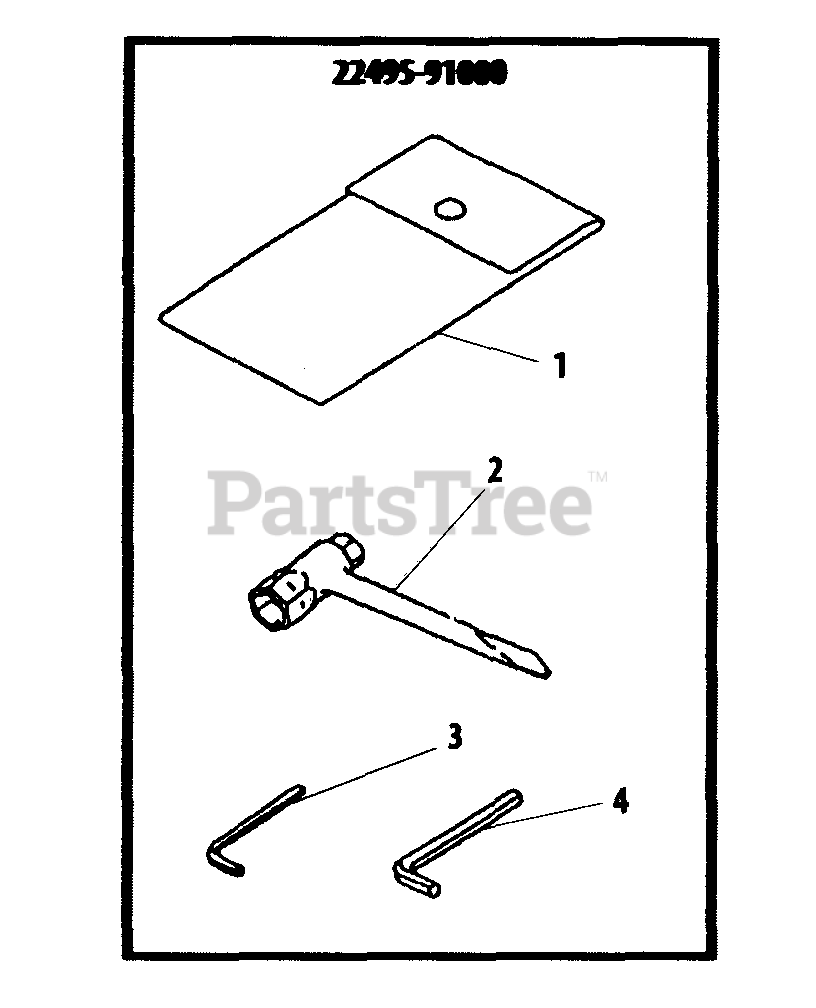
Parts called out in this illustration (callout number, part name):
1	BAG, TOOL
2	T-WRENCH - 13X19mm
3	HEX KEY - 3mm
4	HEX KEY - 4mm
22495-91000	TOOL KIT
